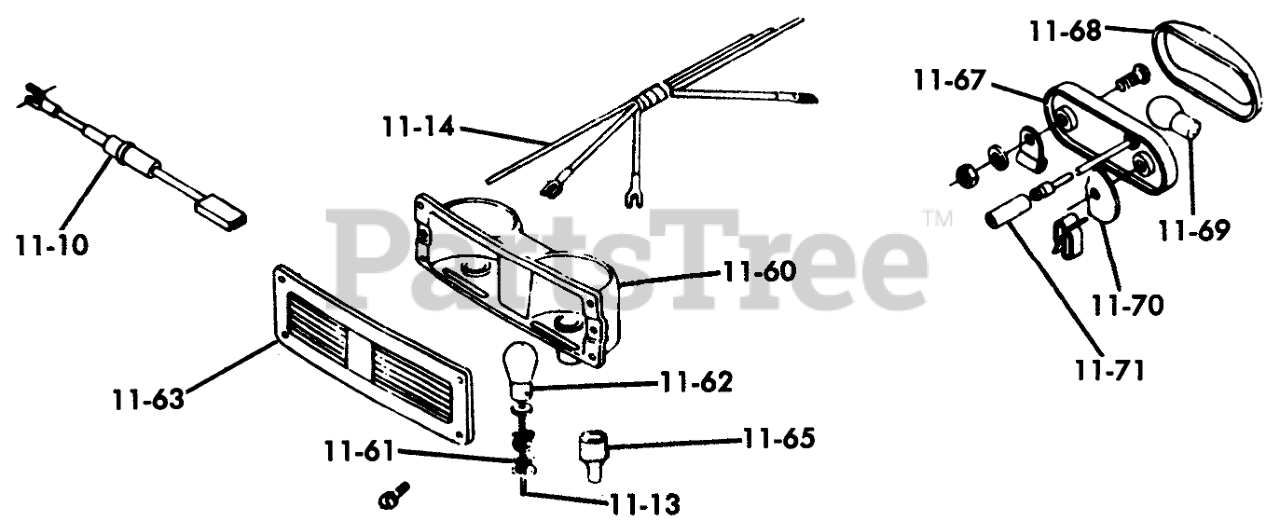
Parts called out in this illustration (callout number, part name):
11-60	ASSY REFLECTOR HOUSI
11-61	SPRING
11-62	BULB
11-63	Lens
11-65	CONNECTOR 3 WIRE
11-67	Base
11-68	Lens
11-69	Bulb
11-70	Mounting Pad
11-71	CONNECTOR 2 WIRE
